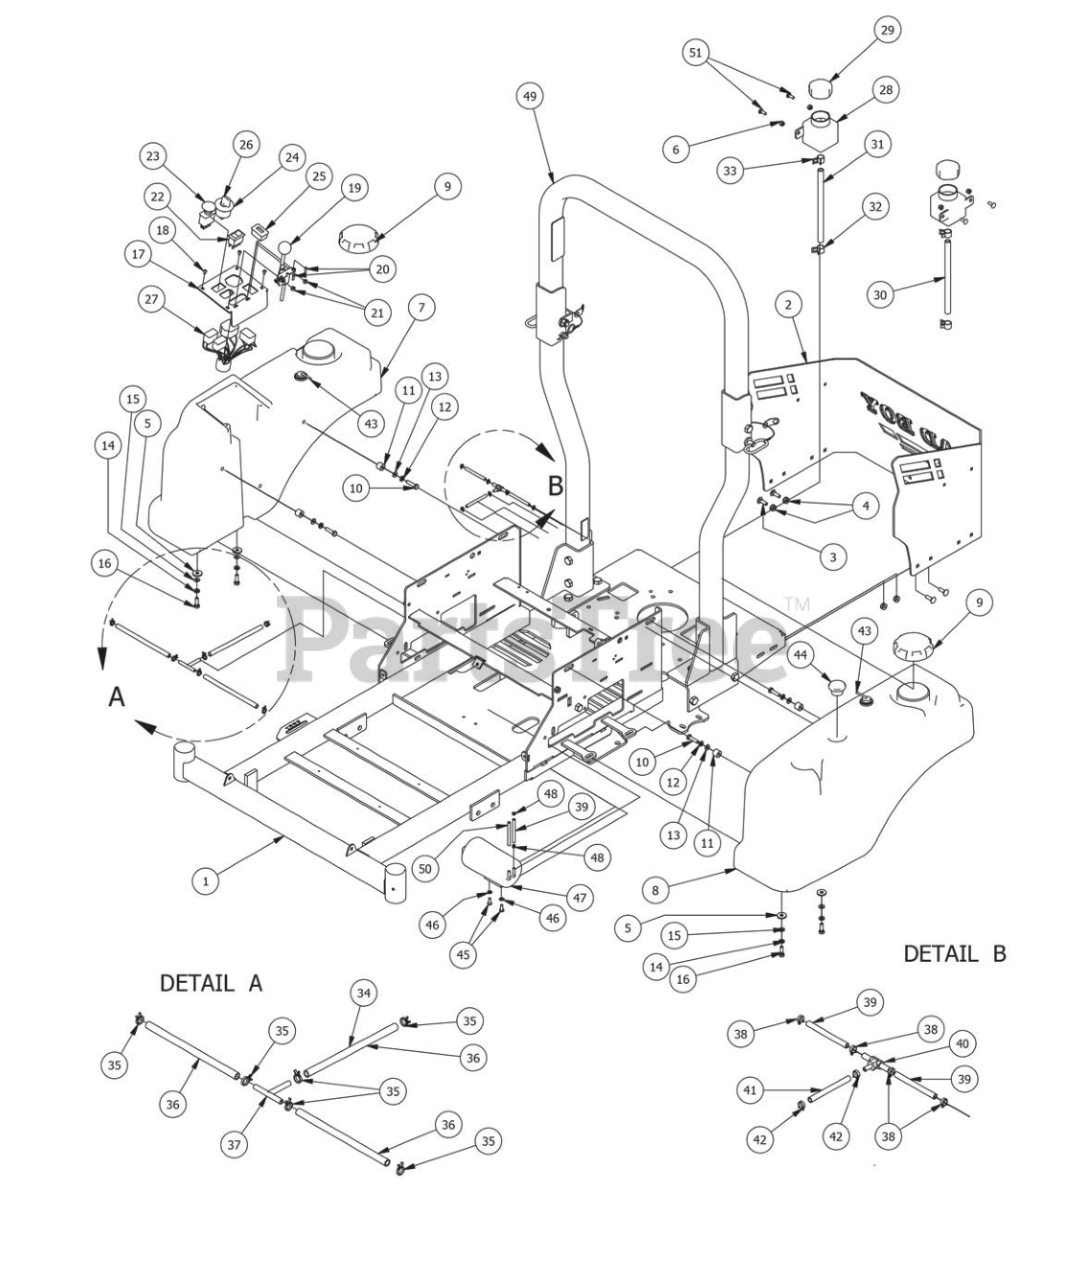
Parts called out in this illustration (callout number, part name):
1	ZT/CZT Frame 2013 Models
2	2014 ZT Rear Plate
3	5/16" x 1" Carriage Bolt
4	5/16-18 Nylon Flange Nut
5	.360 ID Plastic Washer
6	1/4" Nylock Nut
7	Right Fuel Tank/Outlaw/2012/EPA
8	Left Fuel Tank/Outlaw/2012/EPA
10	5/16 x 1 1/4 Hex Bolt
11	.380x.735x.470 Nylon Spacer
12	5/16" Lock Washer
13	1/4" Flat Washer
14	5/16" Lock Washer
15	1/4" Flat Washer
16	5/16" x 1" Bolt
17	2013 ZT/CZT Control Panel
18	10-32 x 3/8" Button Socket Head Bolt
19	Throttle Lever Assembly
20	10-24 X 5/8 BS C/S 18-8 SS
21	10-24 Nylon Insert Locknut
22	Rocker Deck Lift Switch - 2011
23	PTO Engager
24	Ignition Switch
25	Tachometer
26	Ignition Key
27	Harness-ZT Only-2008 and up
28	350ml Expansion Tank-CZT
29	Hydraulic Tank Cap
30	2013 ZT Hydraulic Hose Assembly
31	3/8 clear hose price per foot
32	1/2 Hose Clamp
33	3/8 hose clamp
34	2013 ZT Fuel Line Assembly
35	1/4 fuel clamp
36	1/4" fuel line hose
37	fuel line T
38	3/16 vinyl clamp
39	3/16 vinyl tubing
40	Brass fuel line T
41	1/4" vinyl tubing
42	1/4" vinyl clamp
43	Rollover Valve-White
44	Fuel Gauge Tanks W/downtube
45	M6-1.0 X 16MM Hex Bolt
46	1/4" Lock Washer
47	Carbon Canister ZT,CZT,Outlaw
48	3/16" Vinyl Hose Clamp
49	2013 Floding ROPS CZT/ZT
50	1/4" vinyl tubing
51	1/4" x 3/4" Carriage Bolt
